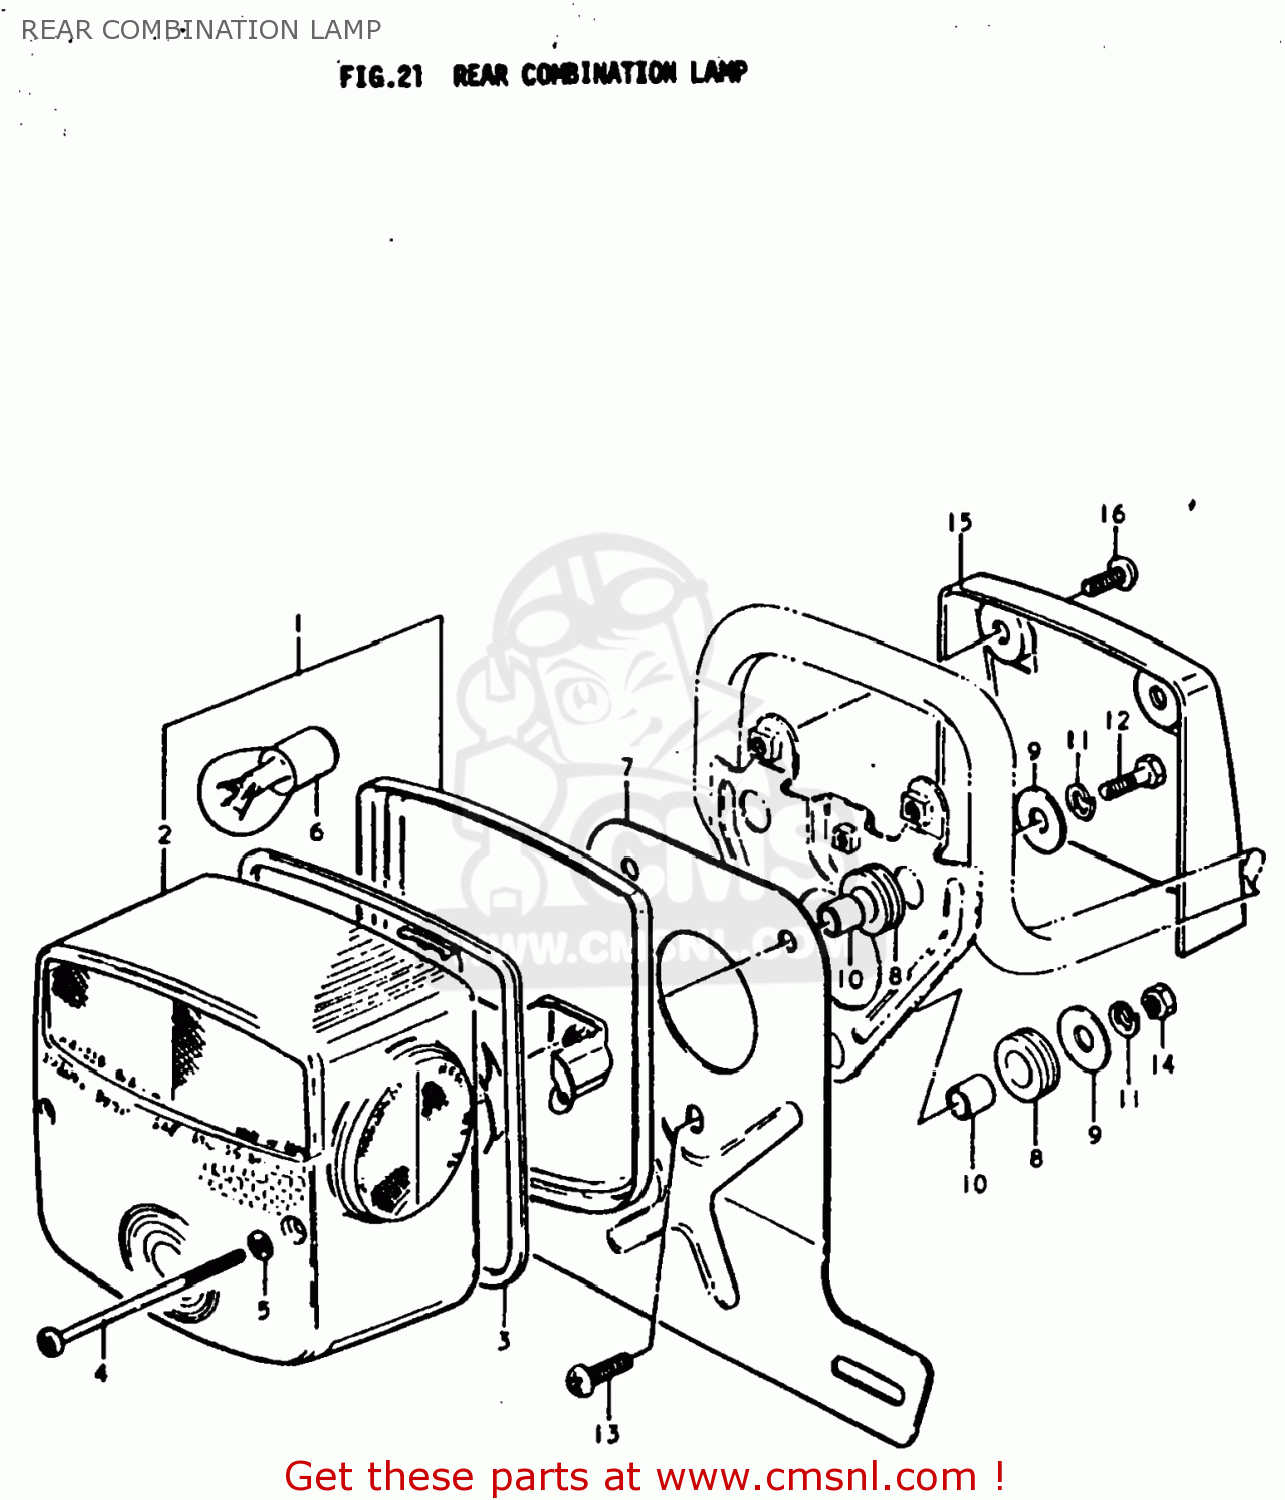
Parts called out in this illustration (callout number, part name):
1	LAMP ASSEMBLY,REAR COMBINATION
2	LENS,REAR COMBINATION LAMP
3	GASKET (NAS)
4	SCREW
5	GASKET (NAS)
6	BULB(6V32/3CP,STANLEY)
7	BRACKET,LICENSE PLATE
8	CUSHION
9	WASHER (6.5X24X1.6)
10	SPACER,REAR COMBINATION LAMP
11	LOCK WASHER
12	BOLT
13	SCREW
14	NUT
15	COVER
16	SCREW
